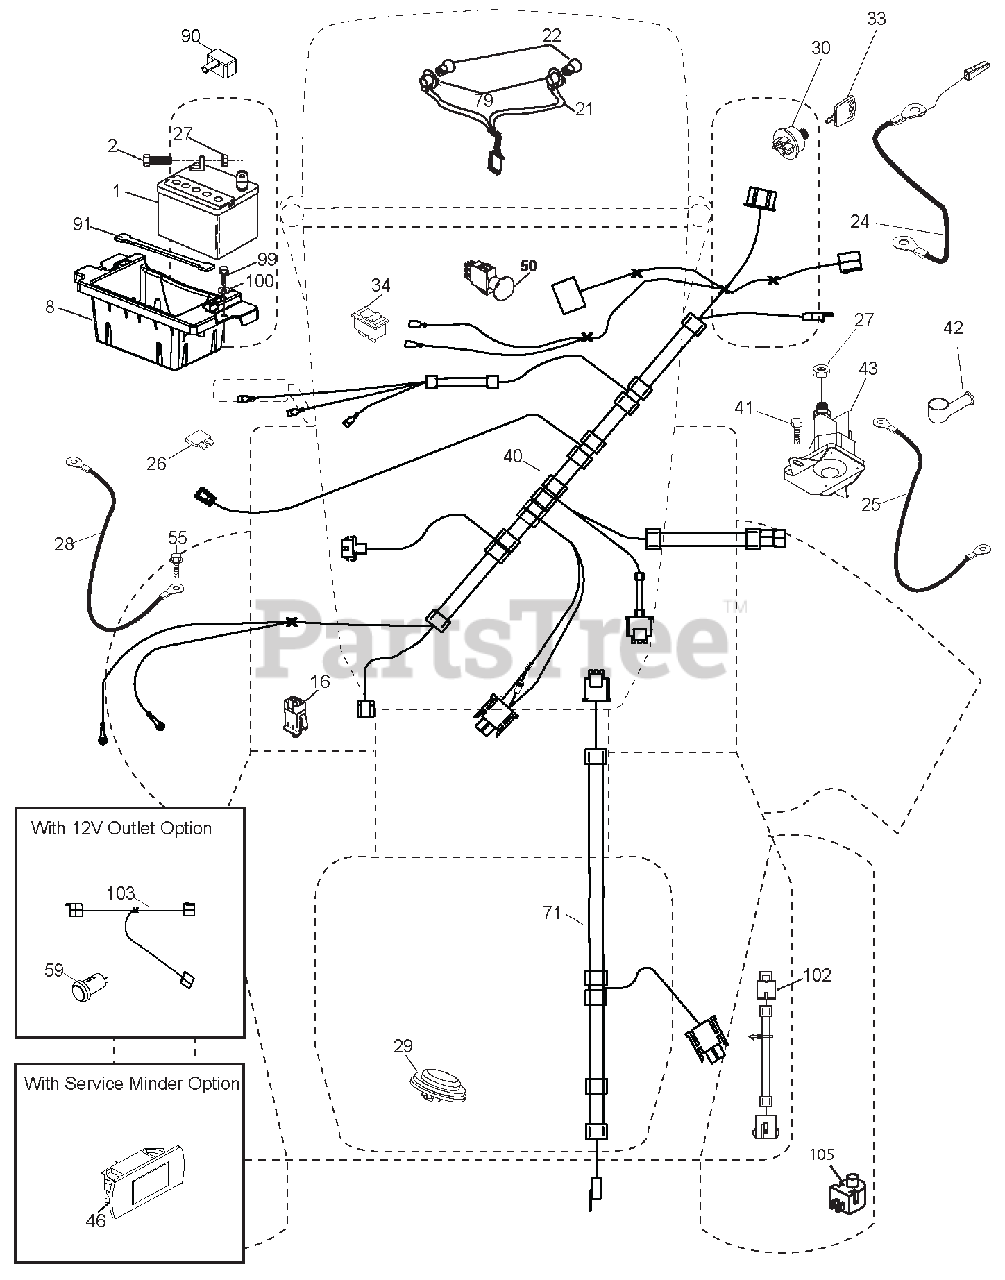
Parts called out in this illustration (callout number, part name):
1	BATTERY.12.VOLT.28.AMP.WET
2	BOLT.HEX.HD.1/4-20UNC X 3/4
8	BOX.BATTERY.MOUNT.FRONT.LT
16	SWITCH.INTERLOCK.NONO.GRAY
21	HARNESS ASM.LIGHT.22"(4152J)
22	BULB.LIGHT.#1156
24	CABLE.BTRY.PSWRE.DSH SOL.8"TEX
25	CABLE STARTER 6 G4. BL/RED14.5
26	FUSE.20 AMP.
27	Nut, Keps Hex 1/4-20 unc
28	CABLE.GROUND.21"BLK.6 GA.90T
29	SWITCH.SEAT.DELTA.OPC.9LB.
30	SWITCH.IGN.DLTA.P-IN.ROS
33	KEY/CHAIN.BLISTER PACK.GEN.USA
34	SWITCH.LIGHT/RESET.B/B/RED.
40	HARNESS.IGN.DASH.HUSQ/PRED.
41	Screw 1/4-20 x 1/2
42	COVER.TERMINAL.RED
43	SOLENOID.W/BRASS PLUNGER.2005
46	HOUR METER
50	SWITCH.PTO.8 TERMINAL.BLACK
55	SCREW.5/16-18X3/4.SMGML.TAP/R
71	HARNESS.IGN.CHASSIS.TEX
79	SOCKET ASM.BULB.TWISTLOCK
90	COVER TERMINAL BATTERY FR. TEX
91	STRAP.BATTERY.MOUNT.FRONT
99	SCREW.HEXWSH.THDROL.1/4-20X3/4
100	WASHER.9/32 X 7/8 X 16GA.
102	HARNESS.PIGTAIL.K46.TEX.ROS
105	SWITCH.REVERSE.TT.PEDAL CONTRO
